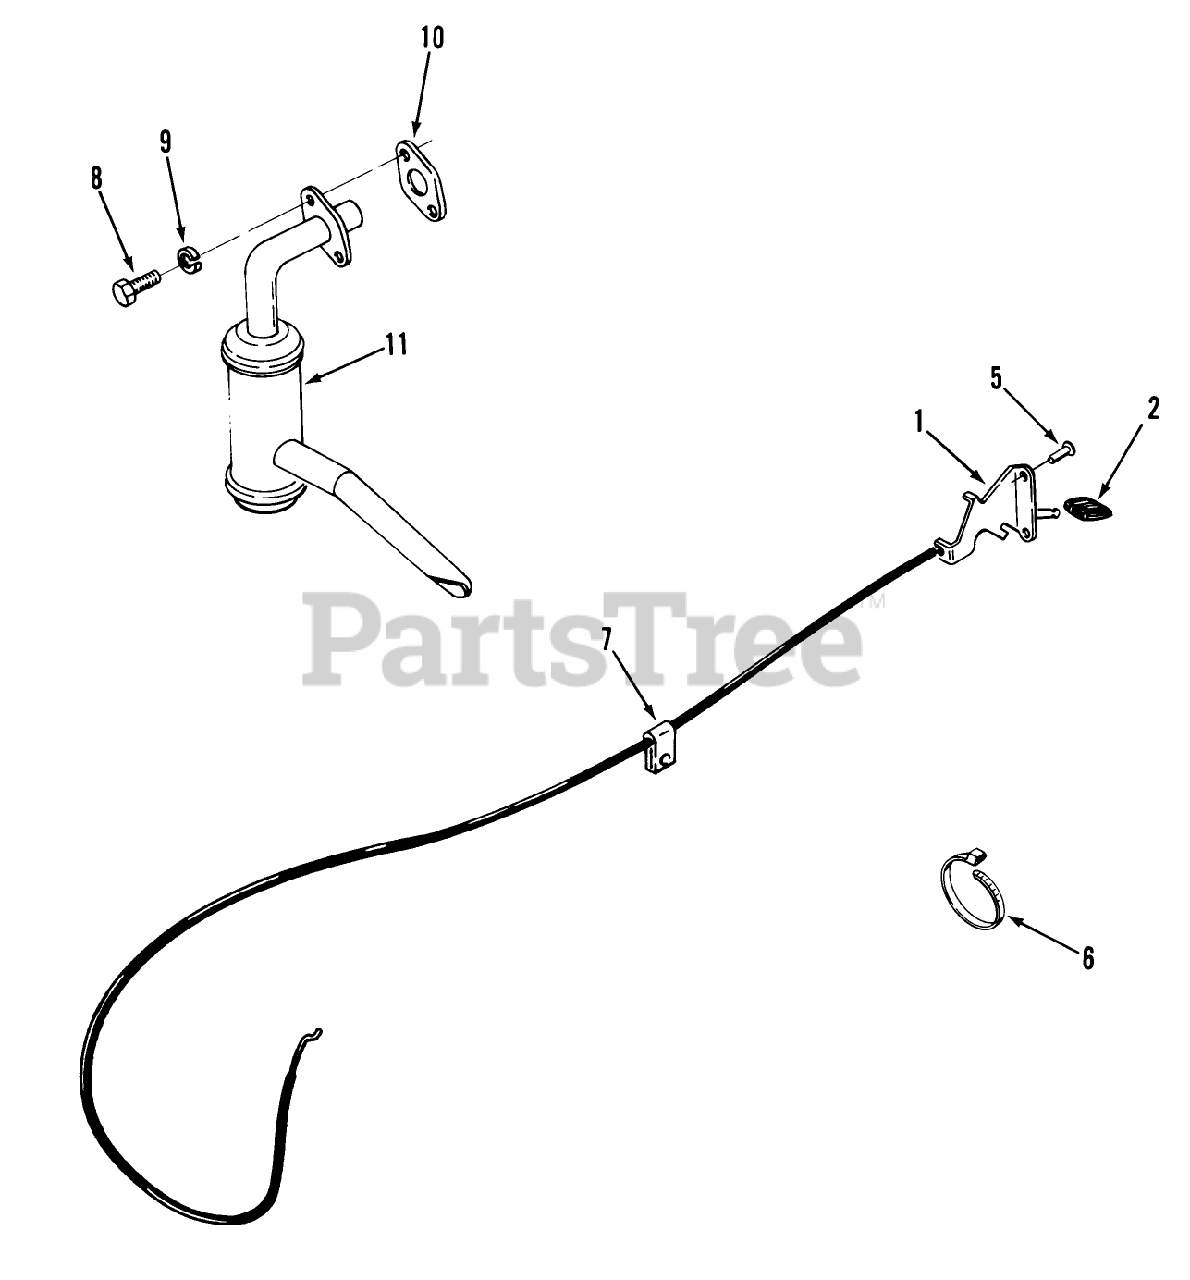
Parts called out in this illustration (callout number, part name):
2	KNOB-THROTTLE
5	Pip Rivet
7	THROTTLE CONTROL CLP
10	USE BRIGGS #270917
